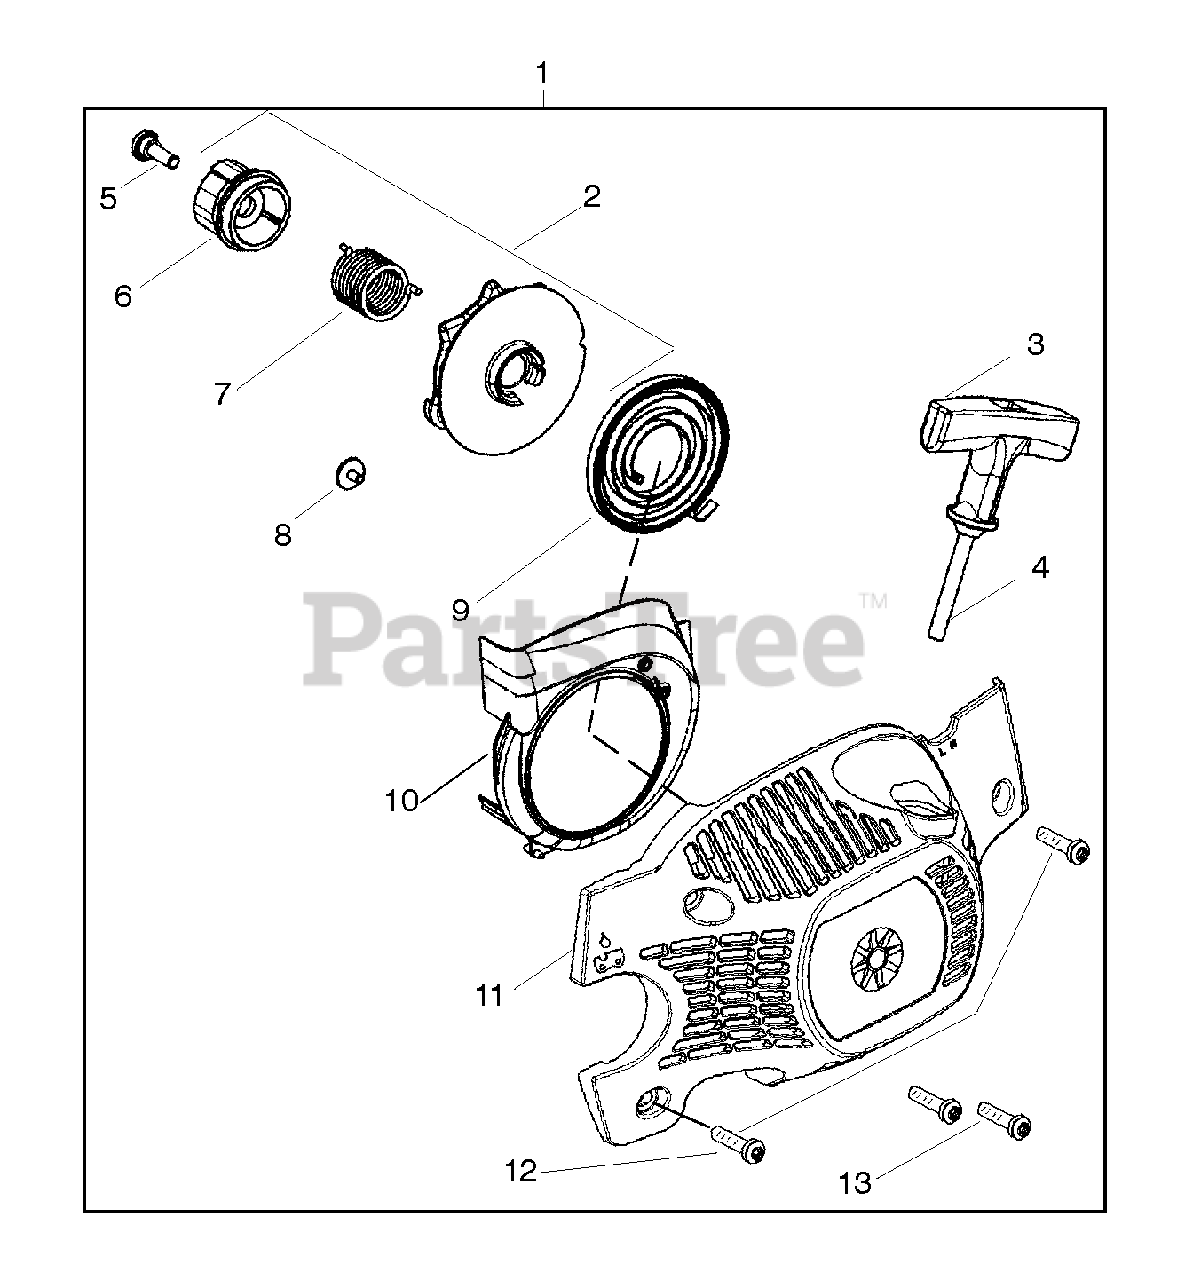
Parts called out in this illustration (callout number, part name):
1	Kit-Fan Hsg / Starter
2	Kit-Starter EPS
3	Handle-Starter
5	Screw-shoulder
7	Spring-EPS
9	Spring-Starter
10	Baffle-Air
11	Assy-Fan Hsg. w/eyelet
